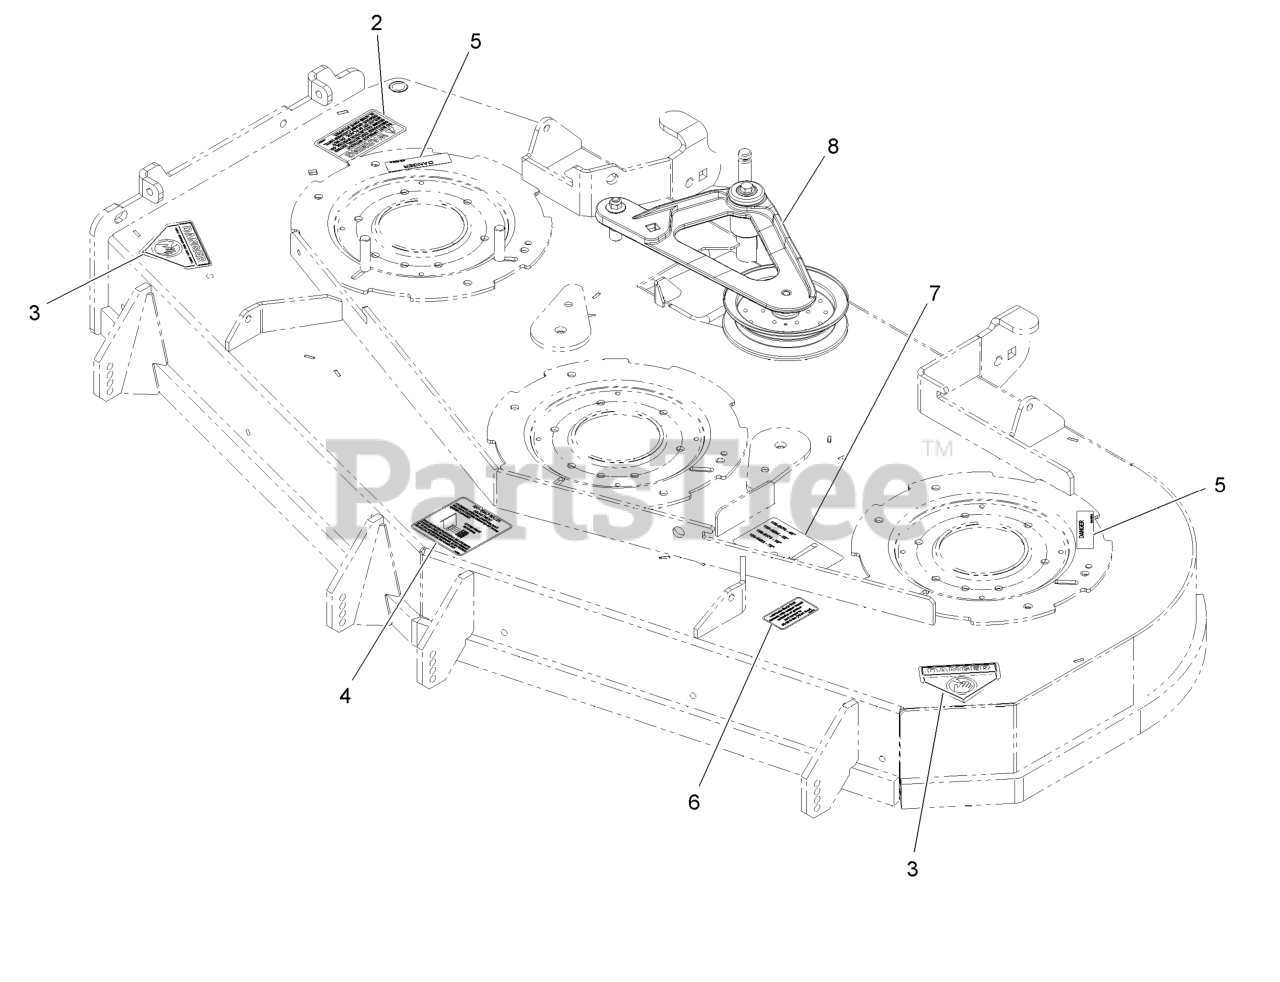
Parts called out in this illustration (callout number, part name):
2	DECAL-WARNING, DISCHARGE
3	DECAL-DANGER
4	DECAL,ANTISCALP
5	DECAL-COVER, MISSING
6	DECAL,BOLT TORQUE
7	DECAL,BELT ROUTING
8	DECK IDLER ASM
